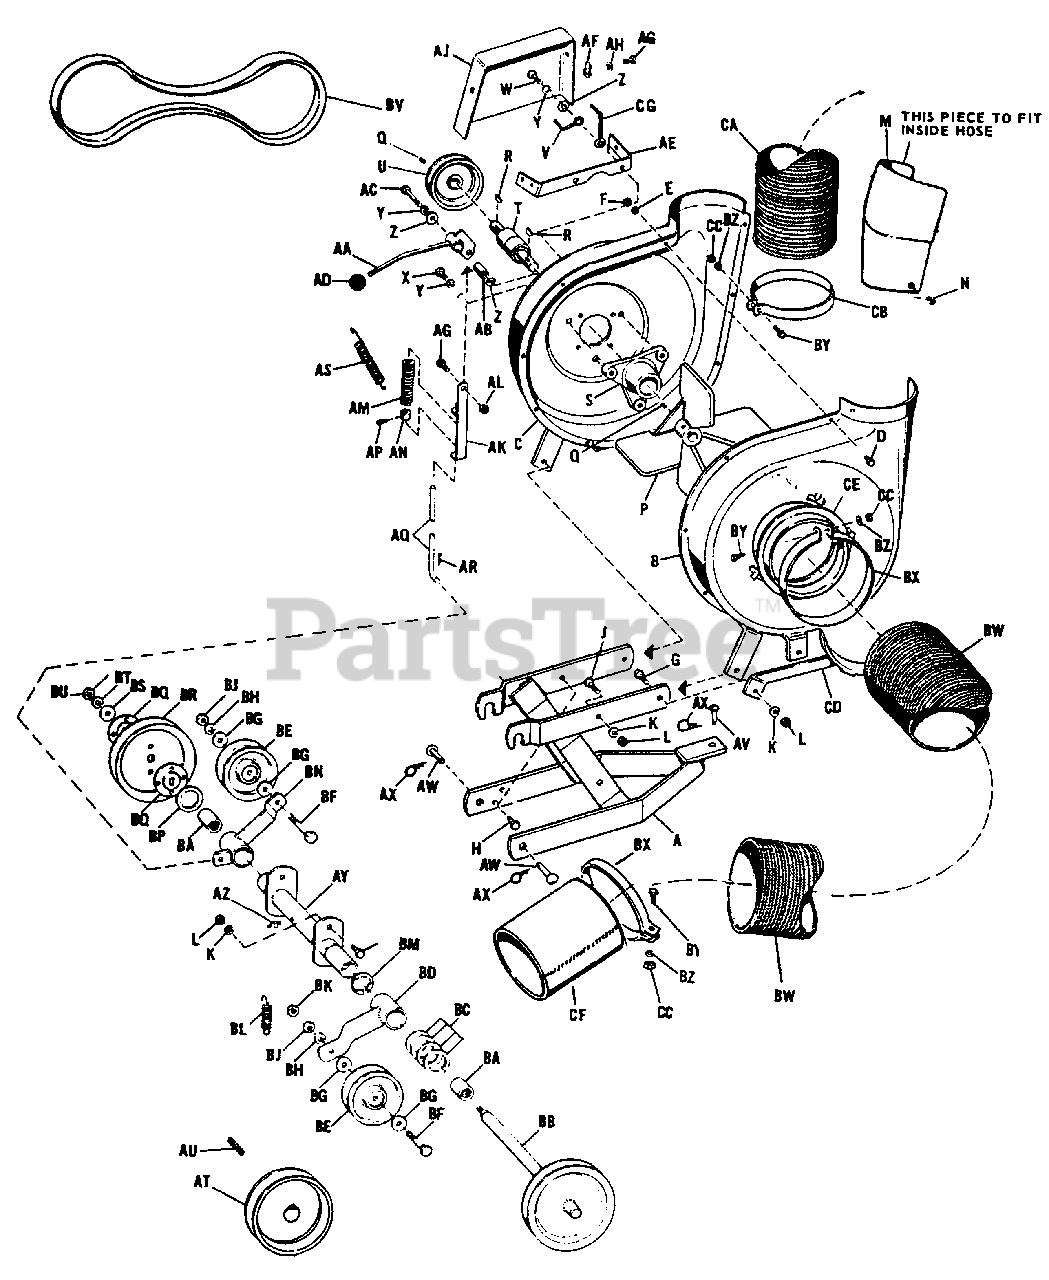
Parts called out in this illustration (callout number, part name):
A	Blower Housing Support Assembly
B	Housing Assembly Inlet Half
C	Housing Assembly R.H. Half
D	Hex Capscrew 1/4-20 x 1/2" lg.
E	Lockwasher 1/4"
F	Hex Nut Full 1/4-20
G	Hex Cap Screw 3/8-16 x 1" lg.
H	Hex Cap Screw 3/8-16 x 1-1/4" lg.
J	Hex Cap Screw 3/8-16 x 1-1/2" lg.
K	Lockwasher 3/8"
L	Hex Nut Full 3/8-16
M	Deflector
N	Screw Self-Tapping #10 x 3/8" lg.
P	Fan Assembly
Q	Set Screw Sq. Hd. 5/16-18 x 1/2" lg.
R	Key Hi-Pro
S	Flange, Shaft and Bearing Assembly
T	Shaft and Bearing
V	Belt Stop
W	Hex Capscrew 3/8-16 x 1-1/2" lg.
X	Hex Capscrew 3/8-16 x 3/4" lg.
Y	Lockwasher 3/8"
Z	Washer Plain
AA	Clutch Lever Assembly
AB	Spacer, Clutch Lever
AC	Hex Capscrew 3/8-16 x 2" lg.
AE	Bracket, Belt Guard
AF	Nut, Retainer
AG	Hex Capscrew 5/16-18 x 5/8" lg.
AH	Lockwasher 5/16
AJ	Belt Guard
AK	Rod Guide Assembly
AL	Hex Nut Full 5/16-18
AP	Set Screw Sq. Hd. 1/4-20 x 3/8" lg.
AQ	Clutch Rod-Blower
AR	Pin 3/32 x 3/4" lg.
AV	Pin
AX	Spring Cup
AY	Bearing Housing Assembly
AZ	Grease Fitting
BA	Needle Bearing
BB	Traverse Shaft Assembly
BD	Tension Arm Assembly
BE	Idler Pulley
BF	Hex Capscrew 3/8-16 x 2" lg.
BG	Plain Washer 3/8"
BH	Lockwasher 3/8"
BJ	Hex Nut Full 3/8-16
BK	Hex Nut Full Lock 3/8-16
BL	Spring Tension
BM	Retaining Ring
BN	Idler Arm Assembly
BQ	Special Washer
BS	Washer Plain
BT	Lockwasher
BU	Hex Nut Full 7/16-14
BV	"V" Belt-P.T.O.
BW	Hose Intake (7" Dia.)
BX	Hose Clamp
BY	Machine Screw Rd. Hd. 1/4-20 x 3" lg.
BZ	Lockwasher 1/4
CA	Hose Exhaust (6" Dia.)
CB	Hose Clamp
CC	Hex Nut Full 1/4-20
CD	Hose Support Assembly
CF	Hose Extension
CG	Belt Stop
